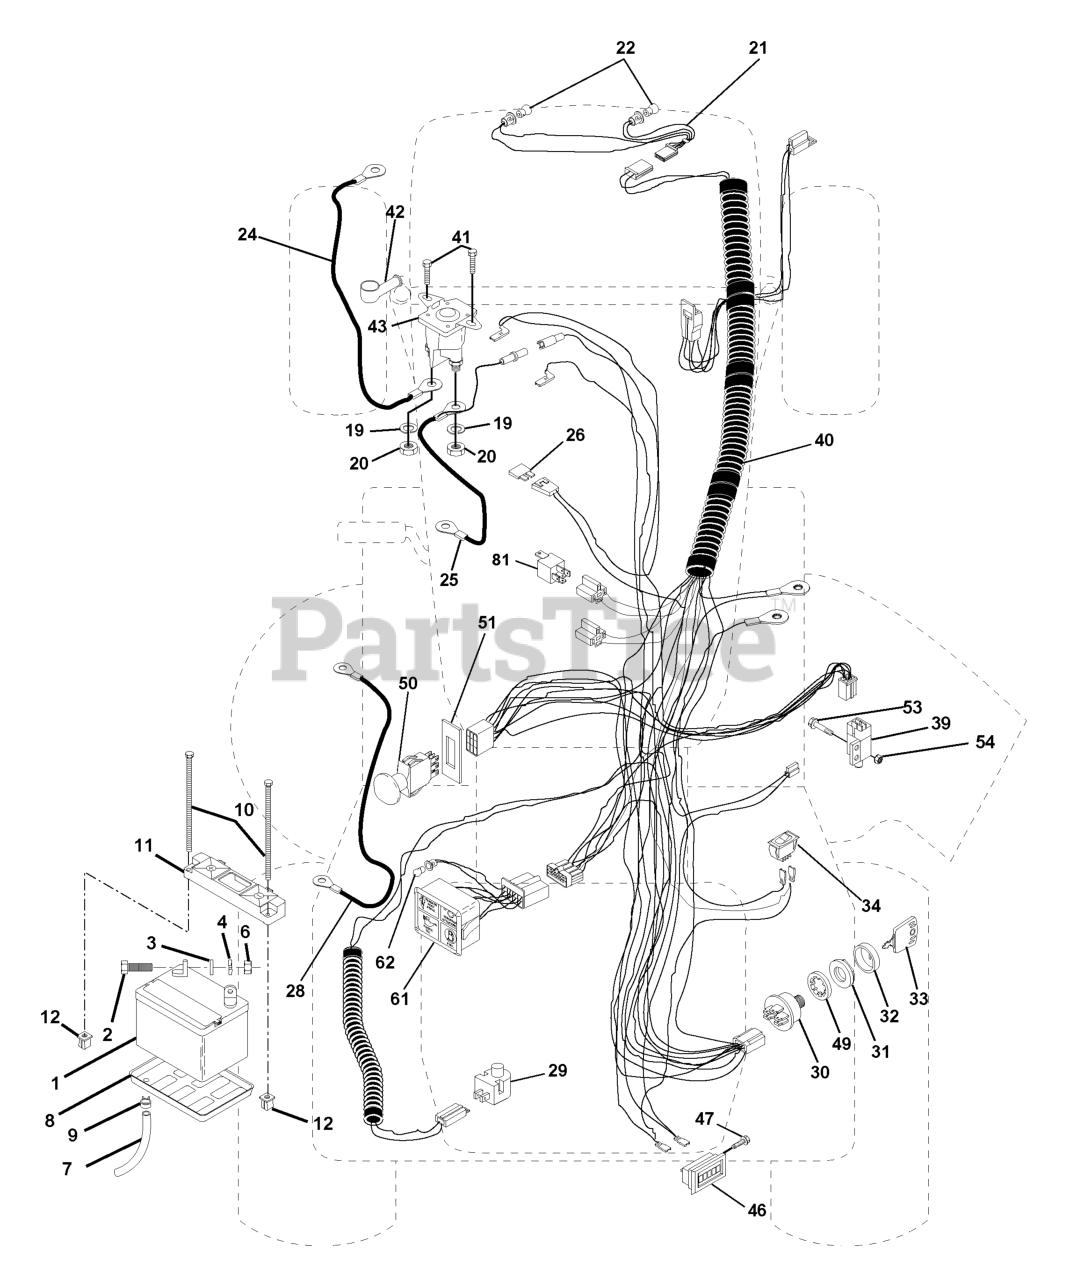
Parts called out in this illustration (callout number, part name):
1	BATTERY
2	BOLT.HEX.1/4.X.3/4.DICHROMATE
3	LOCKWASHER
4	WASHER
6	NUT
7	PLASTIC TUBE
8	BATTERY TRAY T
9	HOSE CLAMP T
10	BOLT 1/4-20 X 7.5
11	HOLDDOWN, BATTERY, DASH MOUNT
12	NUT, PUSH NYLON 1/4" BATTERY
19	LOCKWASHER
20	NUT
21	HARNESS LIGHT SOCKET
24	CABLE, STARTER
25	CABLE, BATTERY
28	CABLE, GROUND
29	RP.SWITCH.PLUNGER.NC.GRAY
30	IGNITION SWITCH
31	NUT, IGNITION
32	COVER SWITCH KEY
33	KEY MLD GEN DELTA
39	SWITCH INTERLOCKT
41	SCREW
42	TERMINAL COVER
43	SOLINOID
46	HOUR METER T
47	Screw #10-24 x 1/2
49	Washer, Pinned Delta
50	SWITCH PTO 3 PDT
51	FRAME RETAINING RING
53	SCREW **
54	Nut Keps #10-32
61	LIGHT PACKAGE
62	BULB LIGHT T
81	RELAY.ASSY.T
